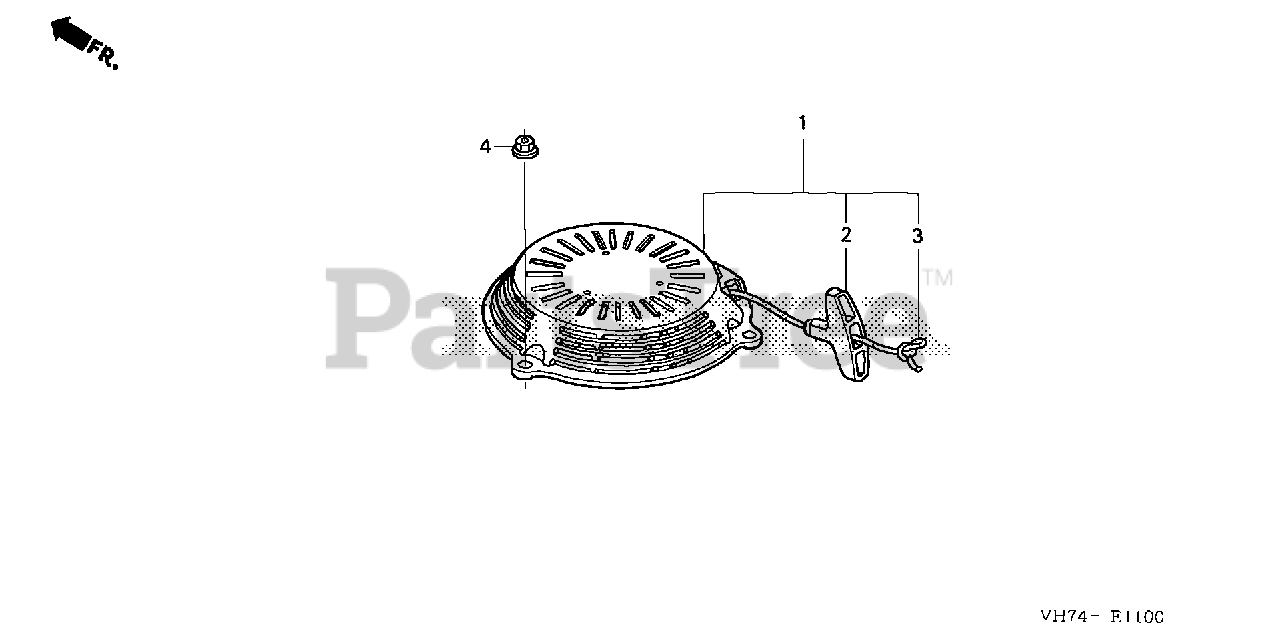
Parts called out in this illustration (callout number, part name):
1	STARTER ASSY., RECOIL *R280* (POWER RED)
2	GRIP, STARTER
3	ROPE, RECOIL STARTER
4	NUT, FLANGE (6MM)
